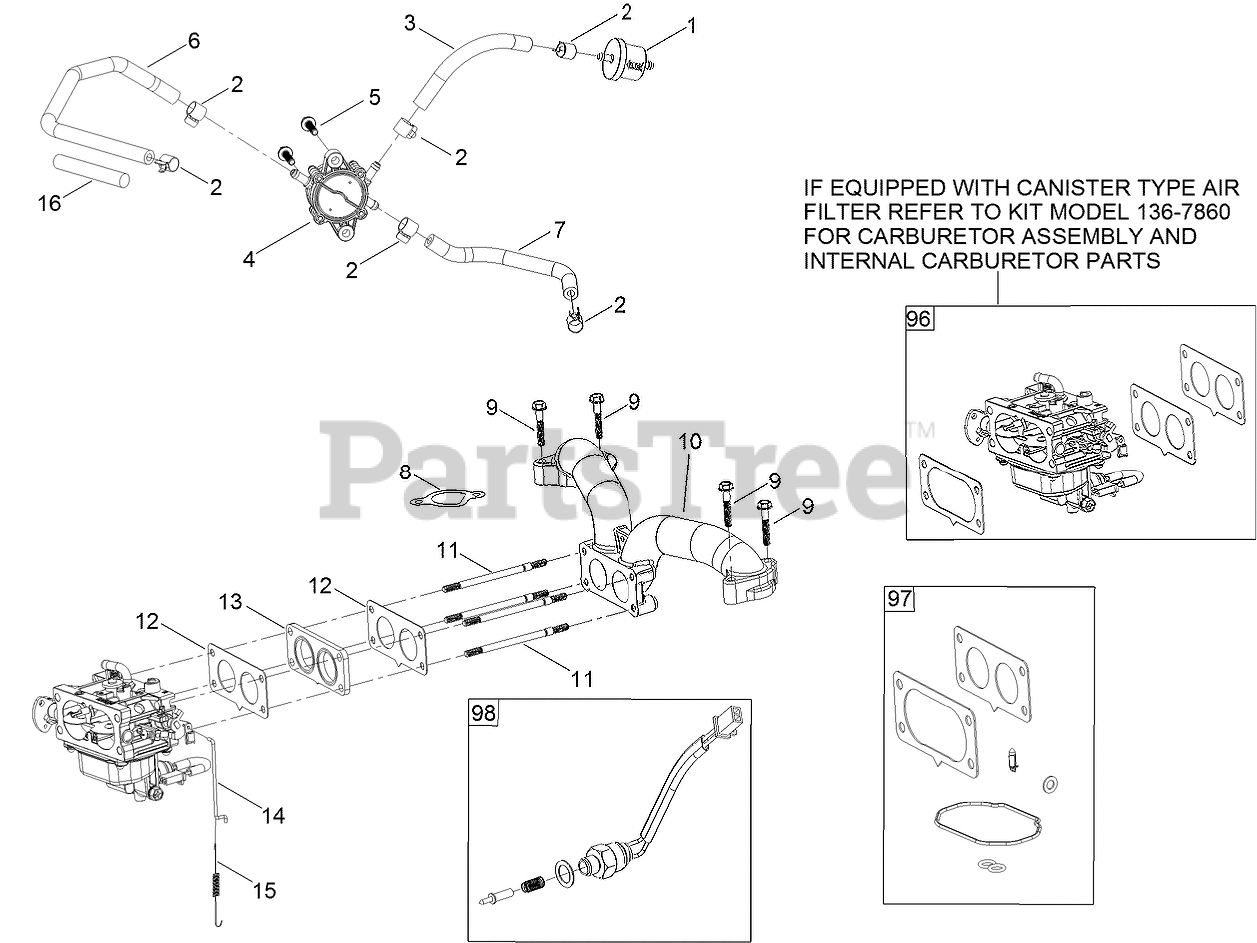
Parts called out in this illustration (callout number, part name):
1	FILTER-FUEL
2	CLAMP-FUEL LINE
3	LINE-FUEL
4	PUMP-FUEL
5	SCREW-HHF
6	HOSE-FUEL
7	HOSE-FUEL
8	GASKET-INTAKE
9	SCREW-HHF
10	MANIFOLD-INTAKE
12	GASKET-CARBURETOR
13	INSULATOR-CARBURETOR
14	LINKAGE-THROTTLE
15	SPRING-RETURN, THROTTLE
16	SLEEVE-FUEL LINE PROTECTO
96	CARBURETOR REPLACEMENT KI
97	CARBURETOR REPAIR KIT
98	SOLENOID KIT
